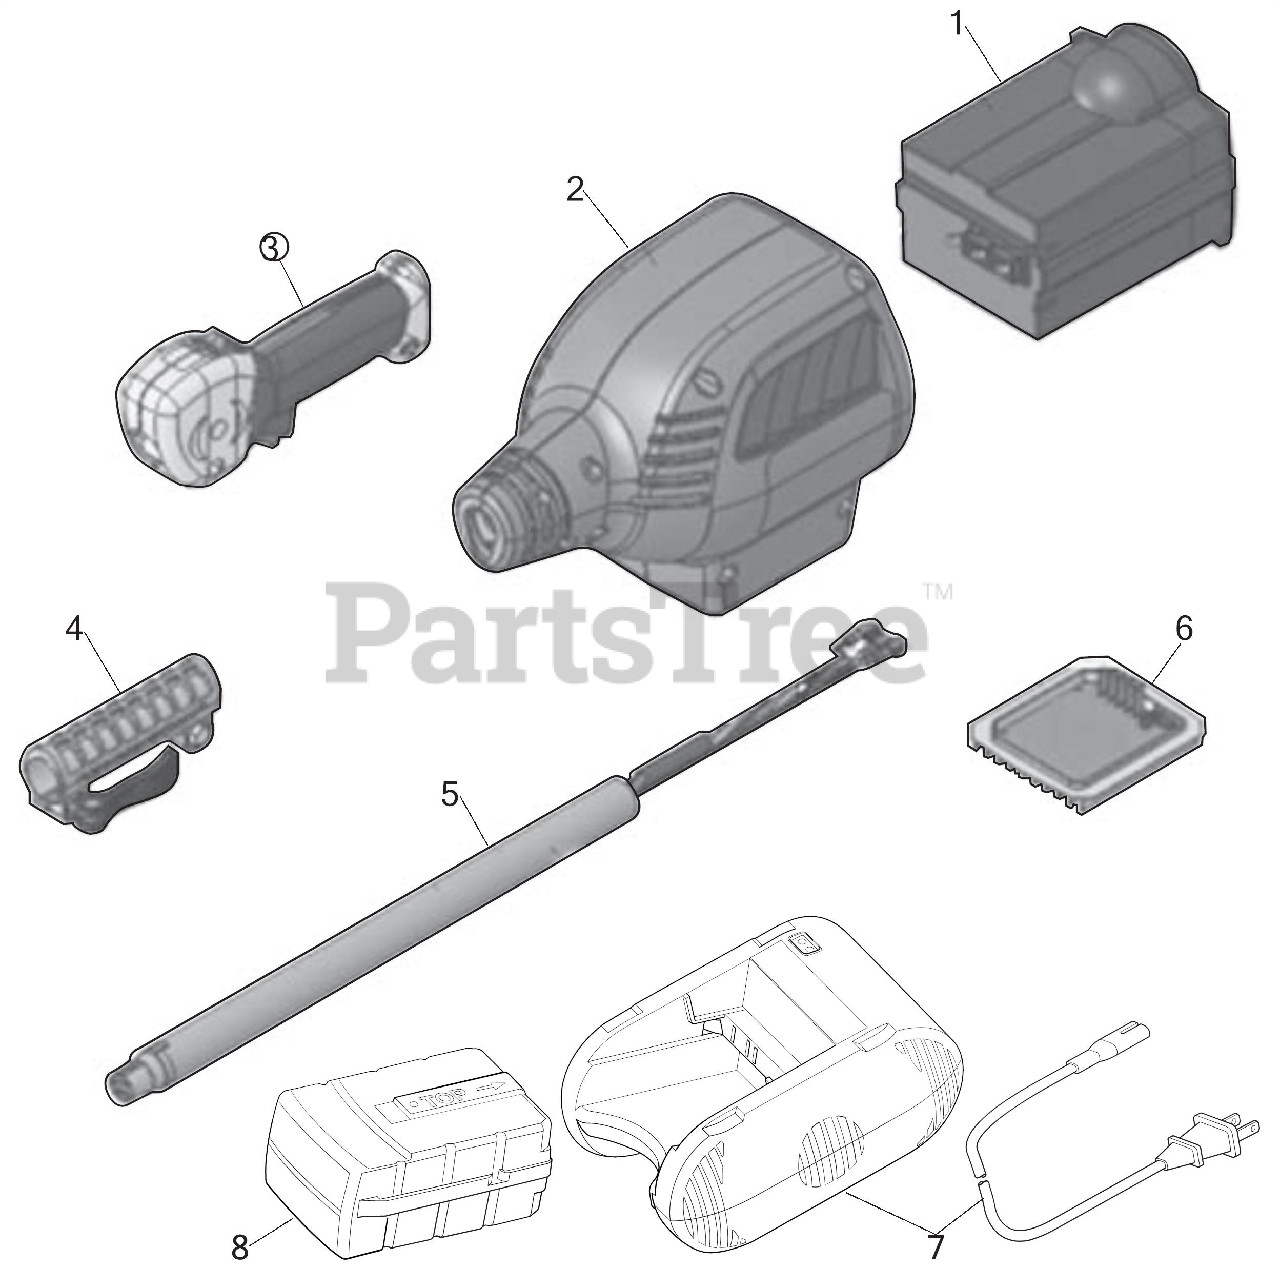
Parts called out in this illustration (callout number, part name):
1	PWR:SLV ASSEMBLY CGT400 CDU400 CORE
2	PWR:HOUSING ASSEMBLY CGT400 CDU400 CORE
3	GRIP ASSEMBLY KIT CGT400 CORE
4	COUPLER SLV ASSEMBLY CDU400 CORE
5	BOOM ASSEMBLY COMP PRL CDU400
6	CONTROLER CDU400 CORE
7	CHARGER 21V 7AH CRC8000 CORE
8	CORE BATTERY 18.5V
